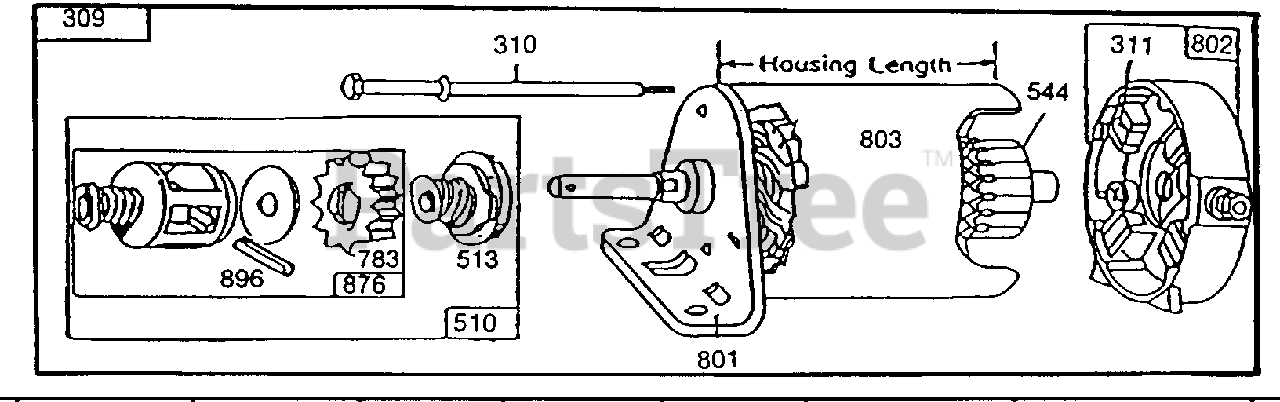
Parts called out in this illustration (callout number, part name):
309	Motor and Drive Ass'y.
310	Thru Bolt Assembly
311	Brush Assembly
510	Drive Assembly
544	Armature Assembly
801	Drive End Cap Assembly
802	End Cap Ass'y. Commutator
803	Housing Assembly, 3-21/32"
